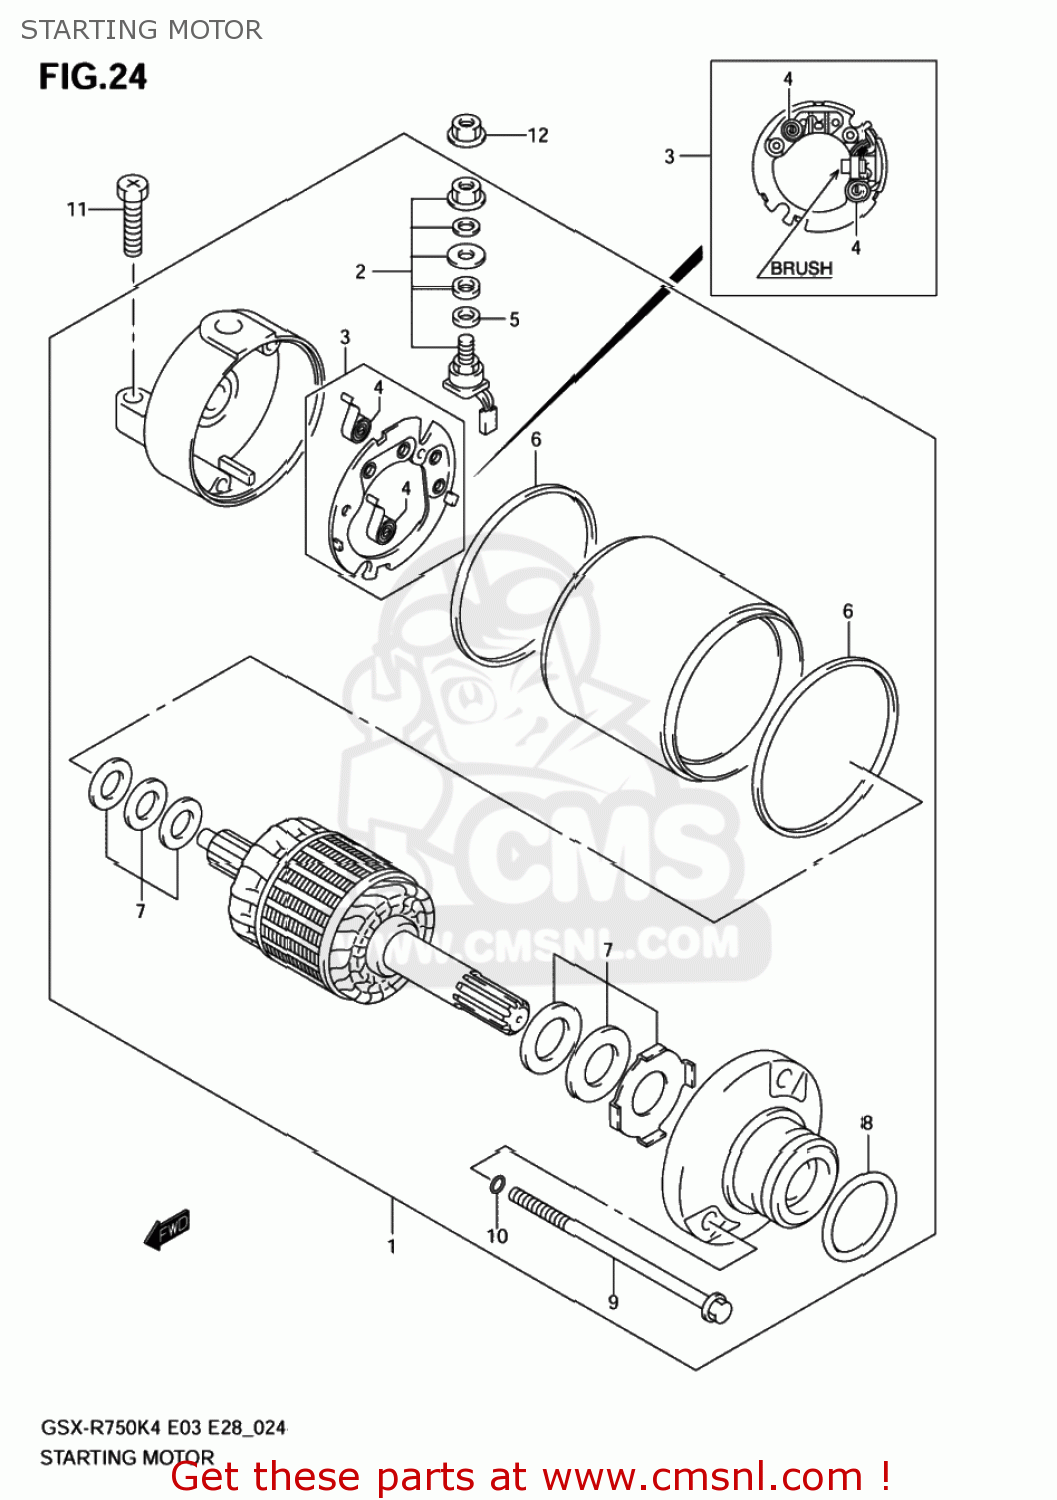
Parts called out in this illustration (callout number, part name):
1	MOTOR ASSEMBLY,STARTING
2	BRUSH TERMINAL SET
3	BRUSH HOLDER SET
4	SPRING,BRUSH
5	O RING
6	O RING
7	SHIM SET,STARTING MOTOR
8	O RING(D:3,ID:24.5)
9	BOLT
10	O RING
11	SCREW (6X25)
12	NUT
